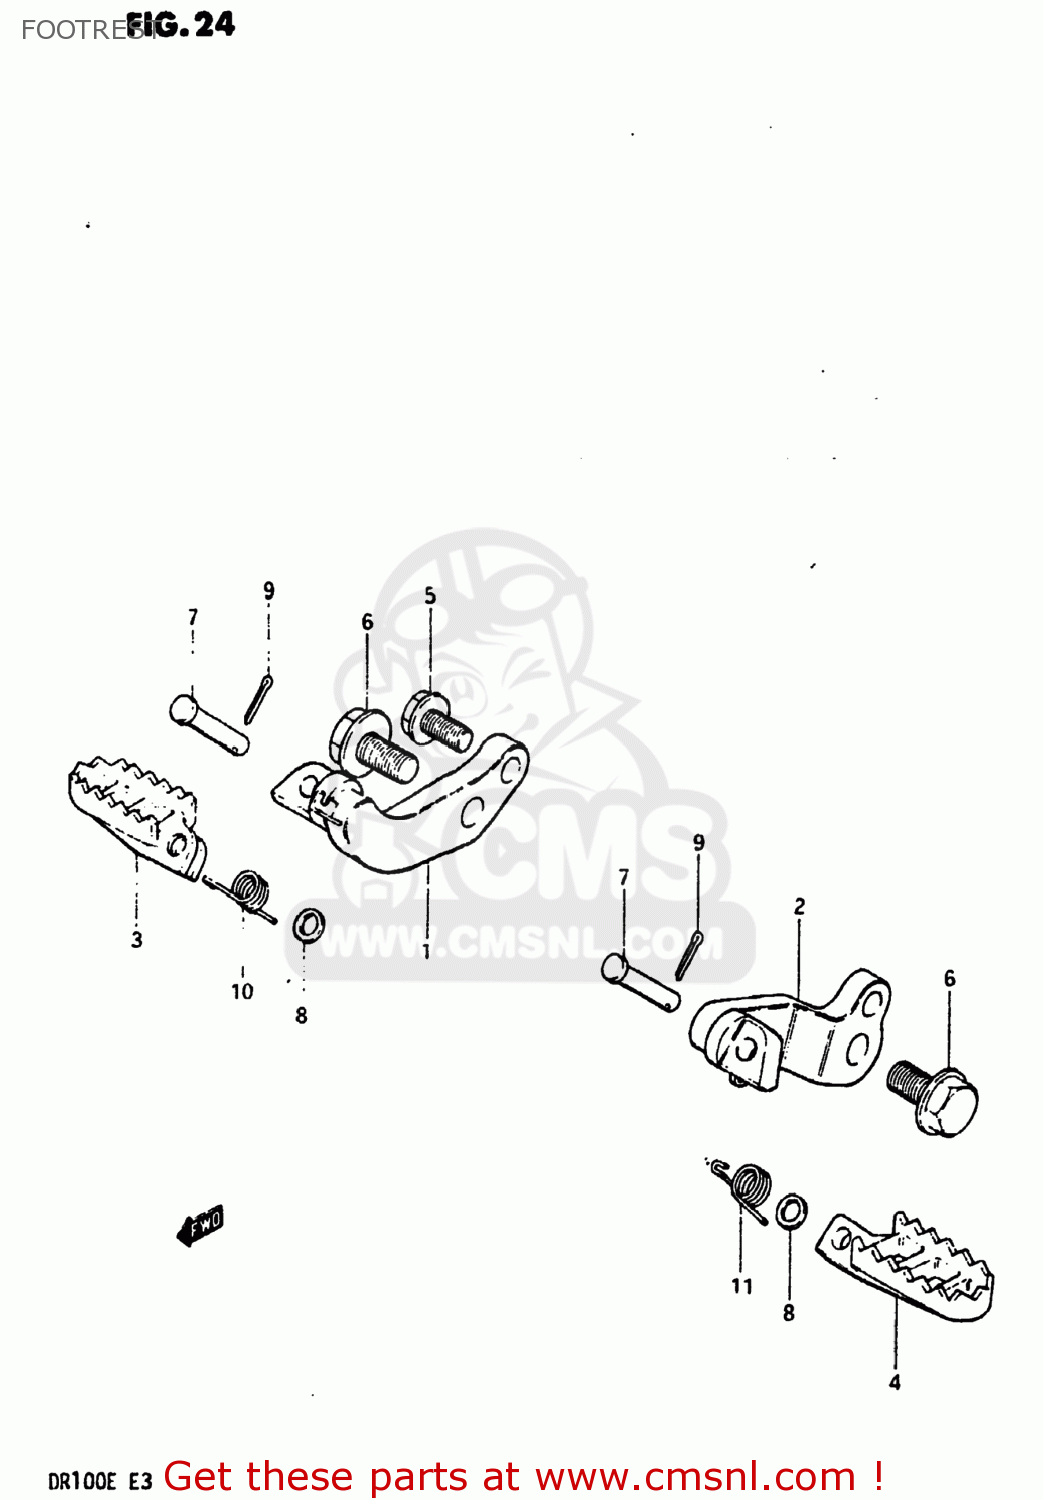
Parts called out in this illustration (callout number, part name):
1	BAR,FRONT FOOTREST
2	BAR,FRONT FOOTREST,LEFT
3	FOOTREST,RIGHT
4	FOOTREST
5	BOLT
6	BOLT
7	PIN
8	WASHER
9	PIN 20X20
10	SPRING
11	SPRING,FOOTREST,LEFT
